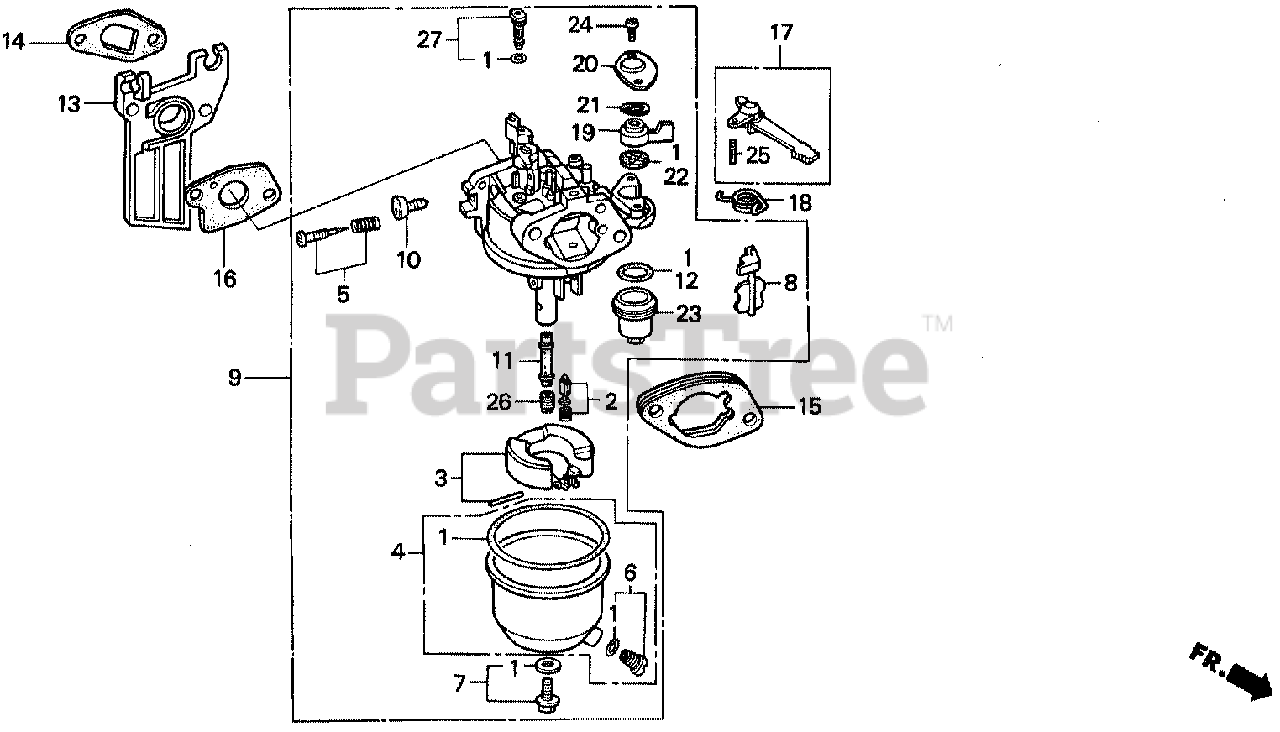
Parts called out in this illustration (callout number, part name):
1	GASKET SET
2	VALVE SET, FLOAT
3	FLOAT SET
4	CHAMBER SET, FLOAT
5	SCREW SET, PILOT
6	SCREW SET, DRAIN
7	SCREW SET B
8	CHOKE SET
9	CARBURETOR ASSY.
10	SCREW, THROTTLE STOP
11	NOZZLE, MAIN
12	GASKET, FUEL STRAINER CUP
13	INSULATOR, CARBURETOR
14	GASKET, INSULATOR
15	SPACER, CARBURETOR
16	GASKET, CARBURETOR
17	LEVER, CHOKE (STD)
19	LEVER, VALVE
20	PLATE, LEVER SETTING
21	SPRING, VALVE LEVER
22	GASKET, VALVE
23	CUP, FUEL STRAINER
24	SCREW, PAN (3X6)
24	SCREW, PAN (3X8)
25	PIN, SPRING (2X12)
26	JET, MAIN (#55)
26	JET, MAIN (#58)
26	JET, MAIN (#60)
27	JET SET, PILOT (#35)
